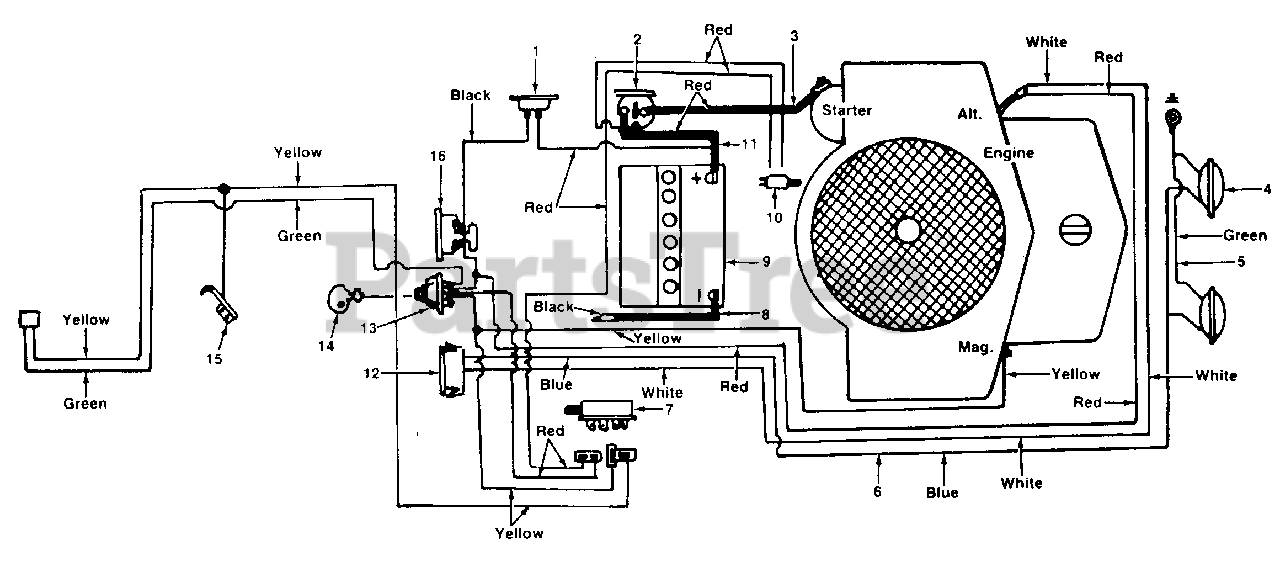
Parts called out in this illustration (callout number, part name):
1	Circuit Breaker
2	Solenoid
3	Wire
4	Headlight
5	Ground Wire
6	Wire Harness
7	Safety Switch
8	6 Ga. Black Wire
9	12V Battery
10	Safety Switch
11	Wire
12	Light Switch
13	Ignition Switch
14	Ignition Key
15	Spring Switch
16	Ammeter
